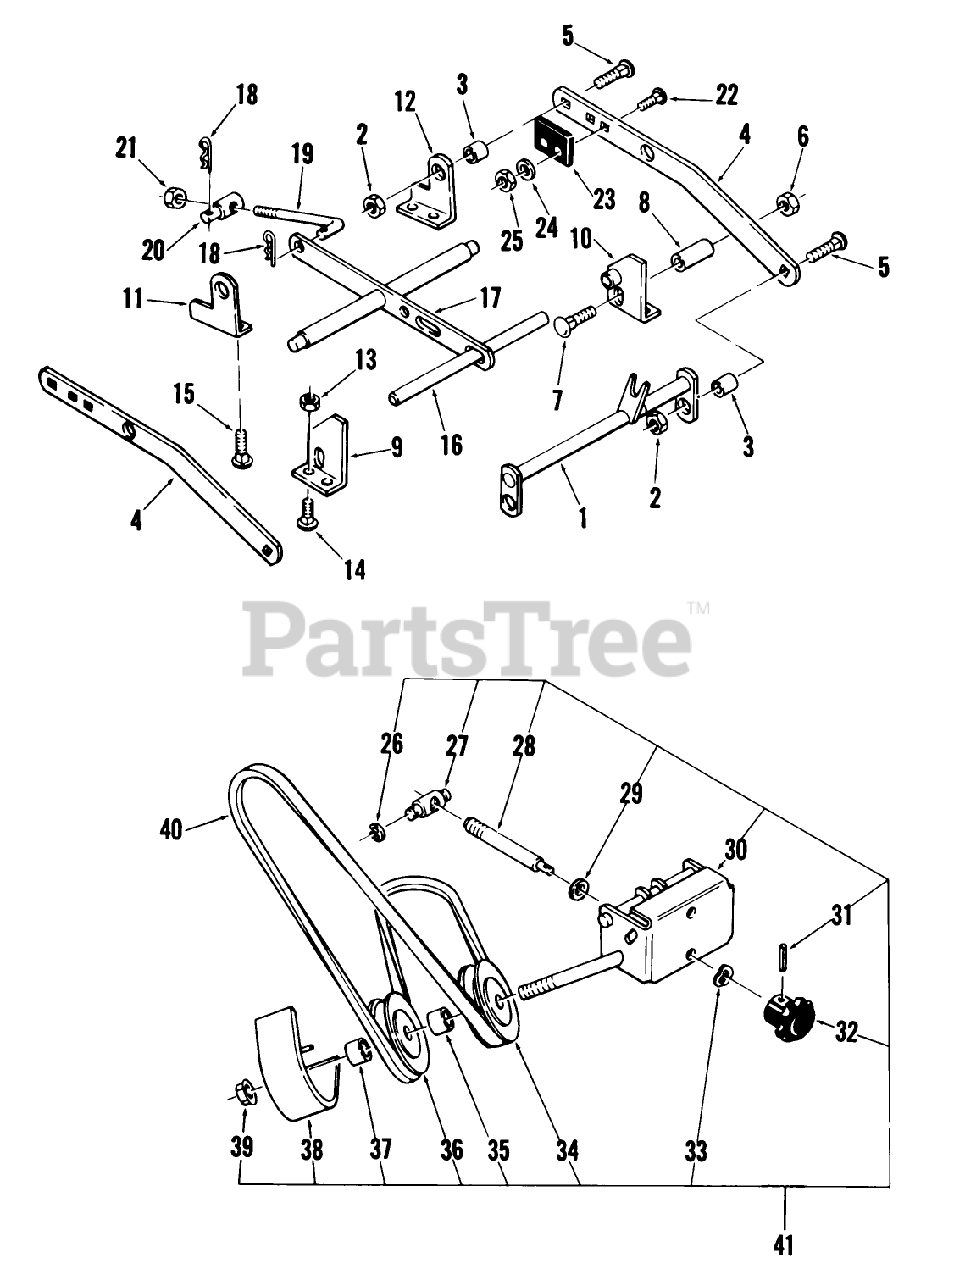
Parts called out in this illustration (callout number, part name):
3	SPACER
7	CARRIAGE BOLT -4
18	Hairpin
19	ROD-LEVEL ADJUST
20	TRUNNION-LIFT
23	BUMPER
26	RING-RETAINING
27	TRUNNION-DOUBLE
28	ROD ADJ
31	PIN-ROLL
32	KNOB-ADJUSTMENT
35	SPACER
36	PULLEY-FLAT IDLER
37	SPACER-OUTER
40	V-BELT
41	ASM-SUPPORT,IDLER
